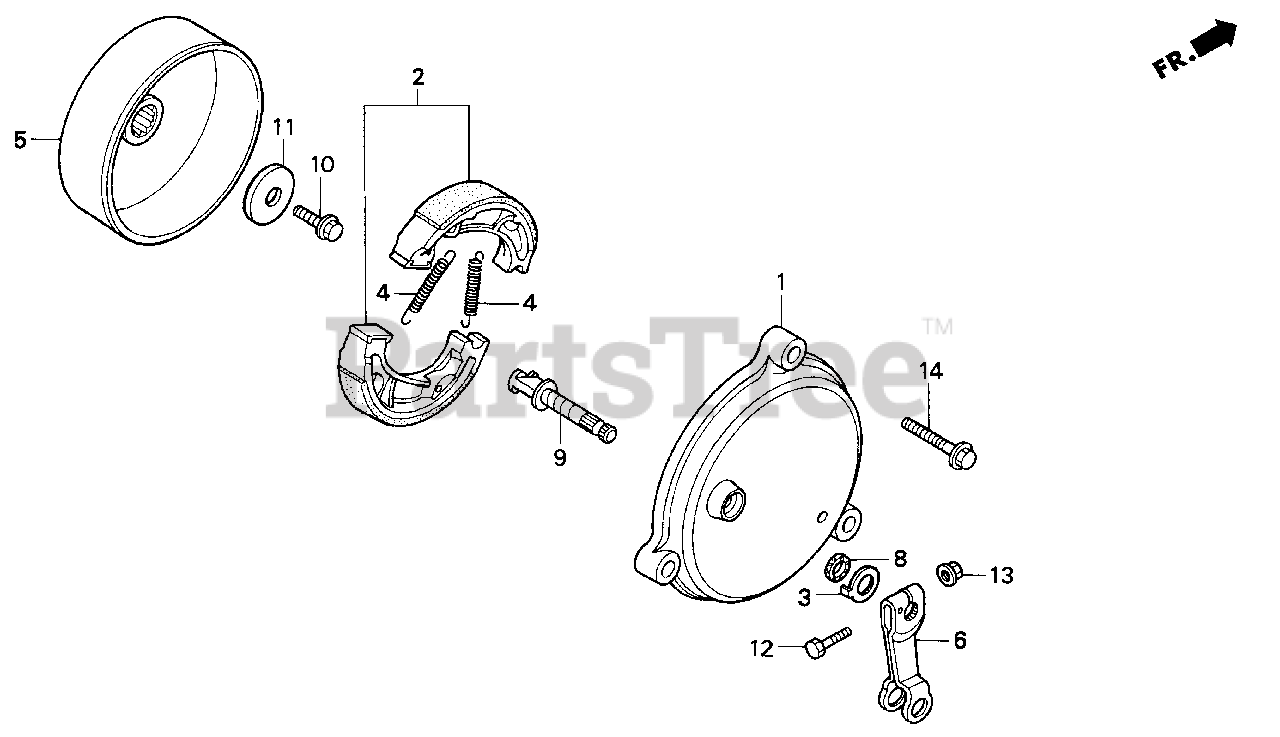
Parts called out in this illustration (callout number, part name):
1	PANEL, BRAKE
2	SHOE SET, BRAKE (ASK)
2	SHOE, BRAKE
3	INDICATOR, BRAKE
4	SPRING, BRAKE SHOE
5	DRUM, BRAKE
6	ARM, RR. BRAKE
8	SEAL, BRAKE CAM
9	CAM, FR. BRAKE
10	BOLT, FLANGE (8X20)
11	WASHER (8.3X24X4.3)
12	BOLT, HEX. (5X25)
13	NUT, FLANGE (5MM)
14	BOLT, FLANGE (8X30)
